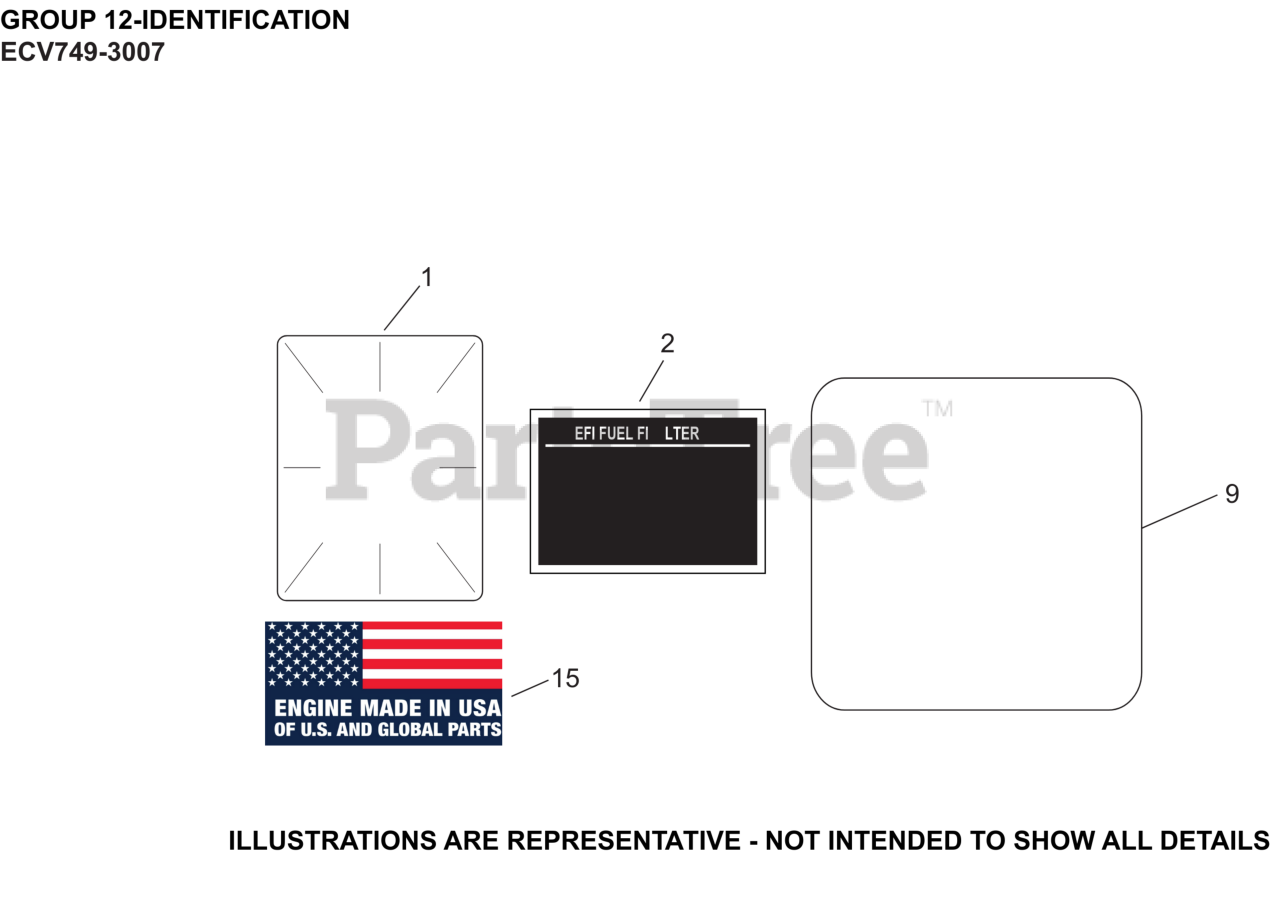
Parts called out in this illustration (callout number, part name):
1	LABEL, CLEAR LAMINATION
2	LABEL, EFI FUEL FILTER
9	DECAL HDAC, ECV749/747cc
15	DECAL, USA
